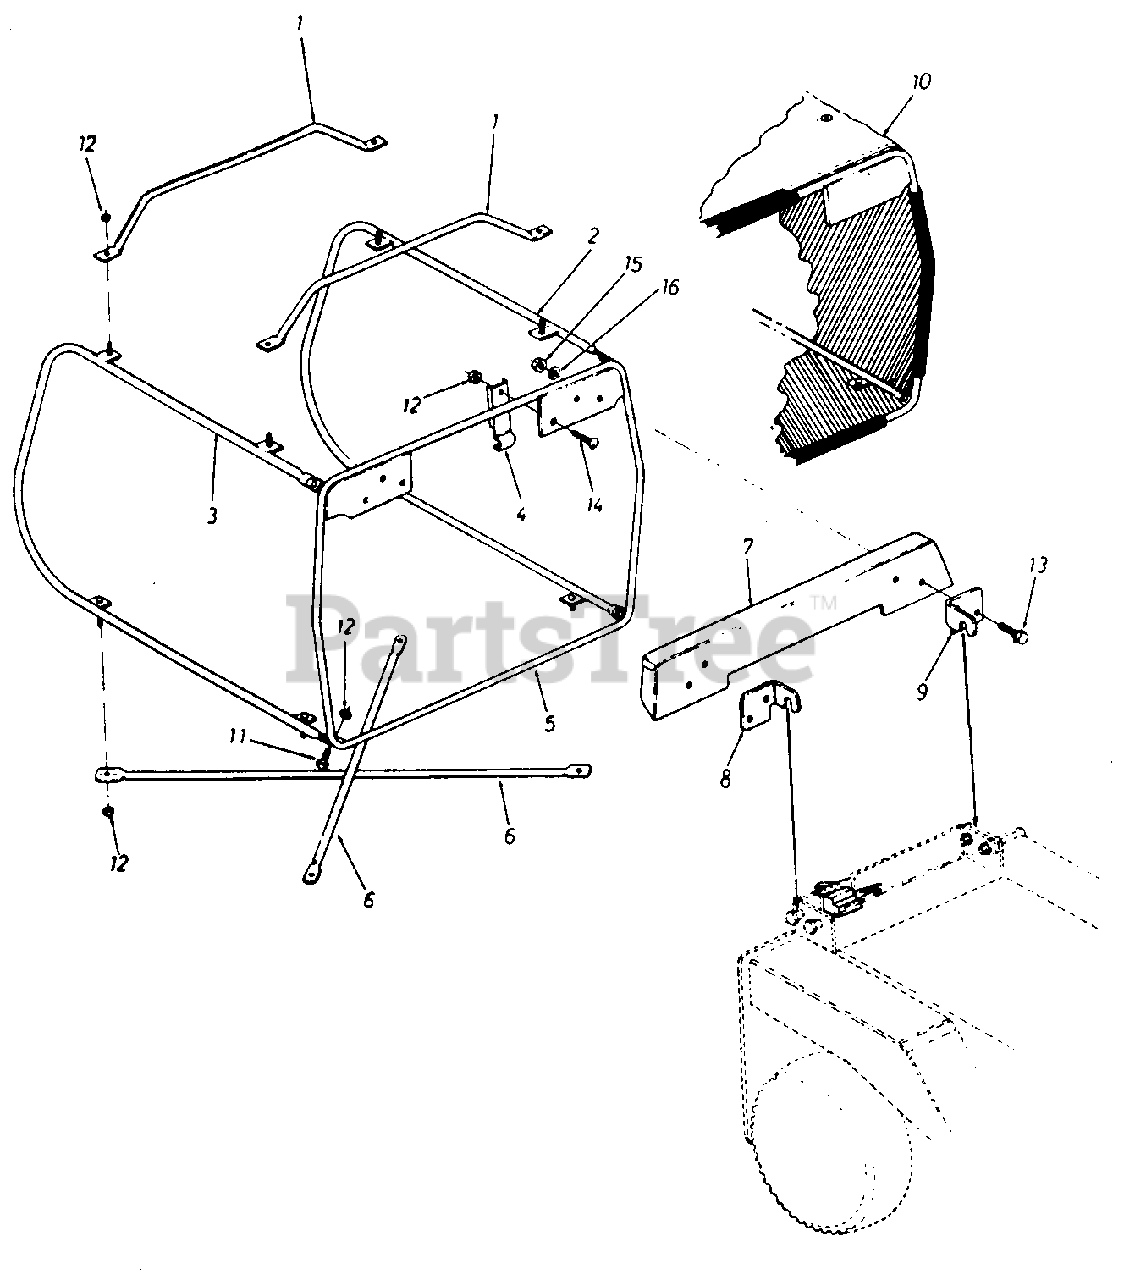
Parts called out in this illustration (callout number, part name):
1	Catcher Handles
2	Catcher Side Frame Ass'y. L. H.
3	Catcher Side Frame Ass'y. R. H.
4	Switch Actuator Bracket
5	Catcher Frame Ass'y.
6	Bottom Cross Brace
7	Dust Cover
8	Hinge-R.H.
9	Hinge-L.H.
10	Grass Bag
11	Hex Scr. 1/4-20 x .62" Lg.*
12	Hex Cent. L-Nut 1/4-20 Thd.
13	Hex Sems Scr. 5/16-18 x 1.00" Lg.*
14	Carriage Bolt 1/4-20 x .62" Lg. *
15	Hex Nut 5/16-18 Thd.*
16	L-Wash. 5/16" Scr.*
